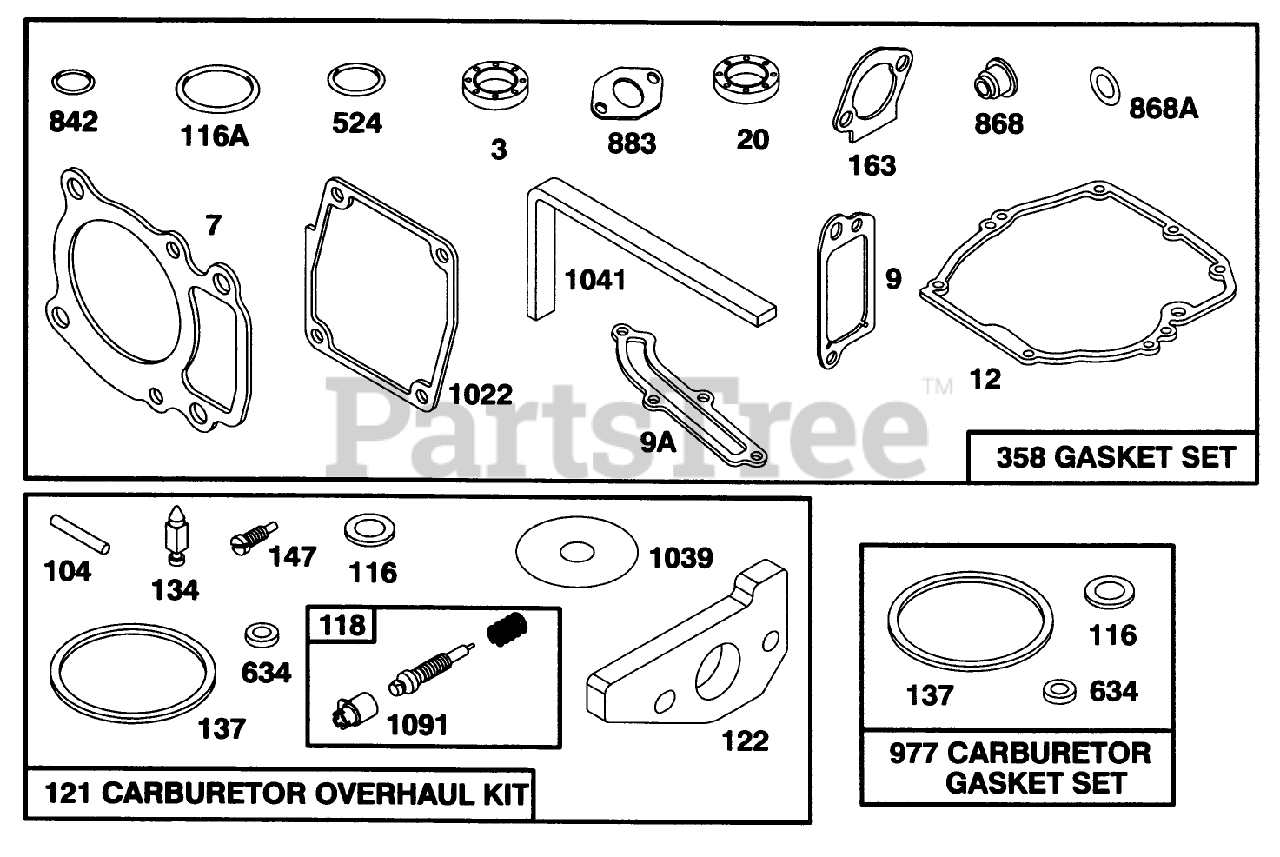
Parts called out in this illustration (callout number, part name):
7	CYLINDER HEAD GASKET
12	ENGINE BASE GASKET
20	SEAL-OIL
116	SEALING GASKET
116A	O RING SEAL
121	KIT-CARBURETOR OVERHAUL
122	ADAPTER ASSEMBLY
134	VALVE-FLOAT
137	FLOAT BOWL GASKET
163	AIR CLEANER GASKET
358	GASKET SET
524	O-RING
842	O-RING
977	CARBURATOR GASKET SET
1022	ROCKER COVER GASKET
1039	FLOAT LIMITER
1091	CAP - LIMITER
